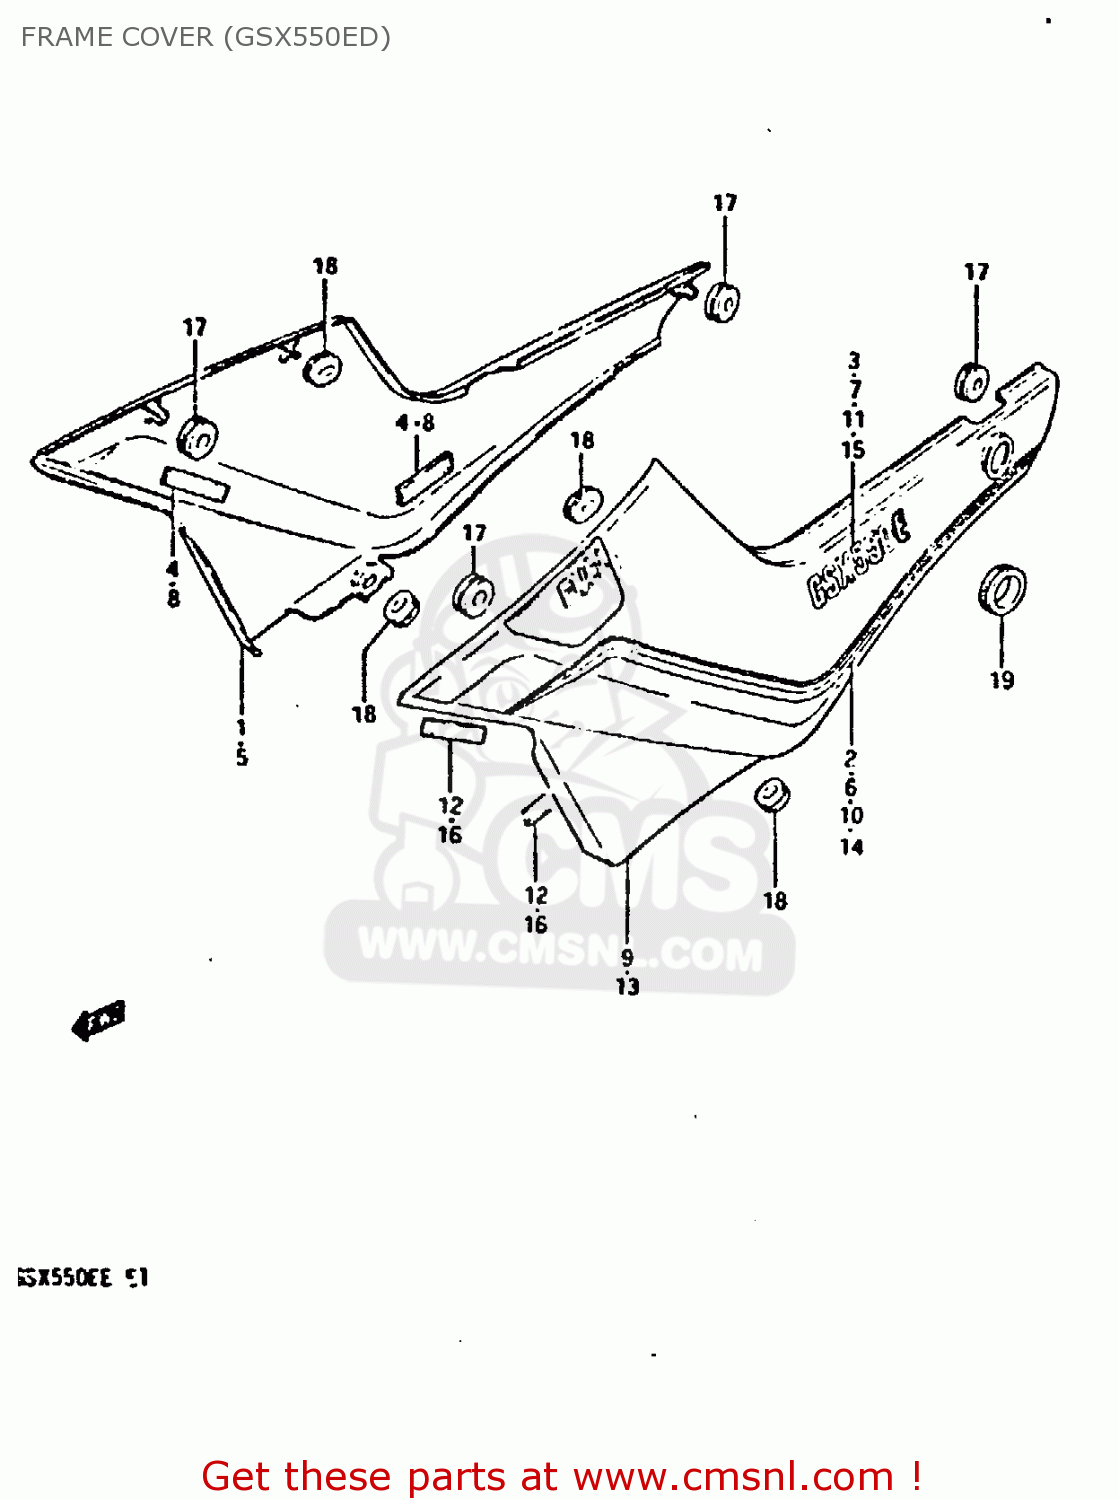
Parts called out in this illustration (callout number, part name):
1	COVER SET, FRAME RH
2	TAPE SET,FRAME COVER
3	EMBLEM
4	RUBBER,FRAME COVER
5	COVER SET, FRAME RH
6	TAPE SET,FRAME COVER
7	EMBLEM
8	RUBBER,FRAME COVER
9	COVER SET, FRAME LH
10	TAPE SET,FRAME COVER
11	EMBLEM
12	RUBBER,FRAME COVER
13	COVER SET, FRAME LH
14	TAPE SET,FRAME COVER
15	EMBLEM
16	RUBBER,FRAME COVER
17	CUSHION
18	CUSHION
19	GROMMET,SEAT LOCK HOLE
